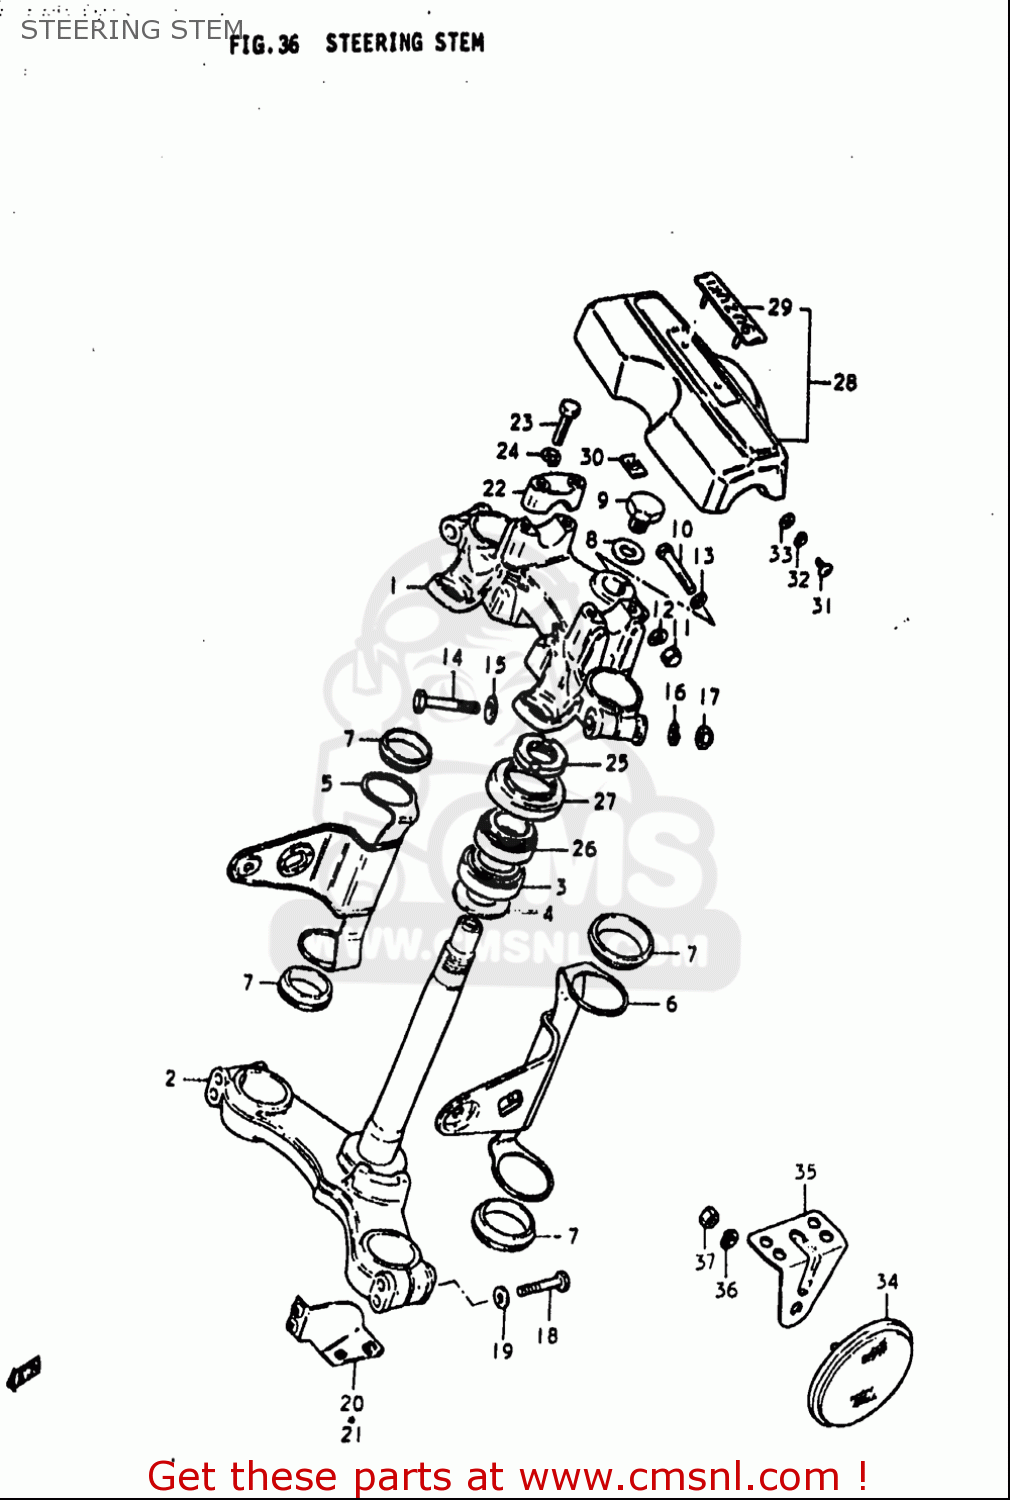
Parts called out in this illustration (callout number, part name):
3	BEARING(30X55X17)
4	SHIM(30X40X1.5)
7	CUSHION,HEADLAMP BRACKET
8	WASHER
9	NUT,FR FORK UPR BRACKET
10	BOLT
11	NUT
12	WASHER,LOCK
13	WASHER
14	BOLT
15	WASHER
16	WASHER,LOCK
17	NUT
18	BOLT
19	WASHER
20	GUIDE,COWLING,RIGHT
21	GUIDE,COWLING,LEFT
22	HOLDER,HANDLE(BLACK)
23	BOLT
24	WASHER,LOCK
25	NUT,STEERING STEM(25X44X10)
26	BEARING(25X47X15)
27	SEAL,STEERING UPR DUST
29	EMBLEM,HANDLE COVER PAD
30	NUT
31	SCREW
32	WASHER,LOCK
33	WASHER
34	REFLEX REFLECTOR,RR
36	WASHER,LOCK
37	NUT
